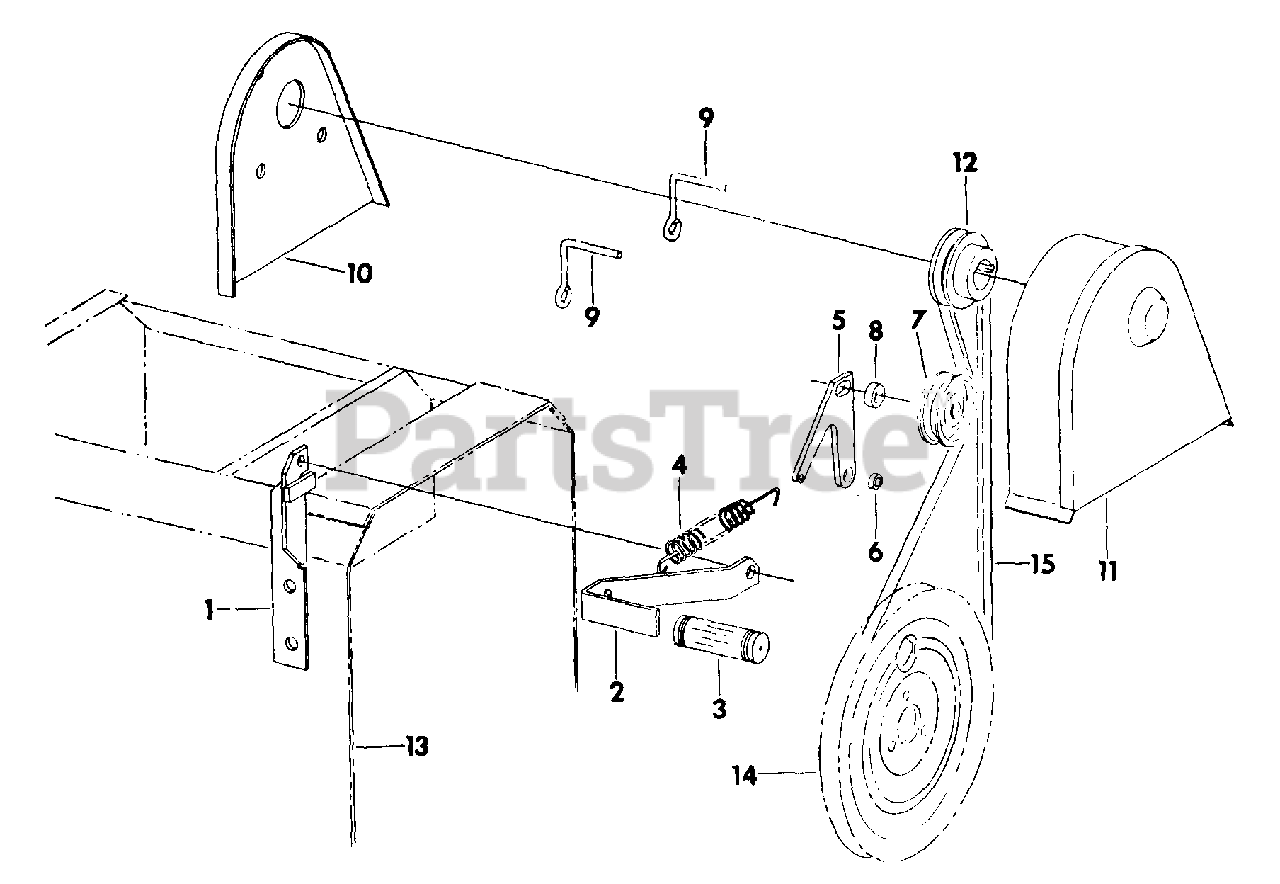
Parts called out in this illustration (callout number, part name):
1	BRACKET, BELT CONTROL
2	LEVER, BELT CONTROL
3	GRIP, RUBBER HANDLE
4	SPRING, BELT TENSION
5	BRACKET, IDLER
7	PULLEY, IDLER
8	SPACER, IDLER MOUNTING
10	PLATE, BELT GUARD BACK
11	PLATE, BELT GUARD FRONT
12	SHEAVE, ENGINE DRIVE
13	HOUSING, WELDED
14	SHEAVE
